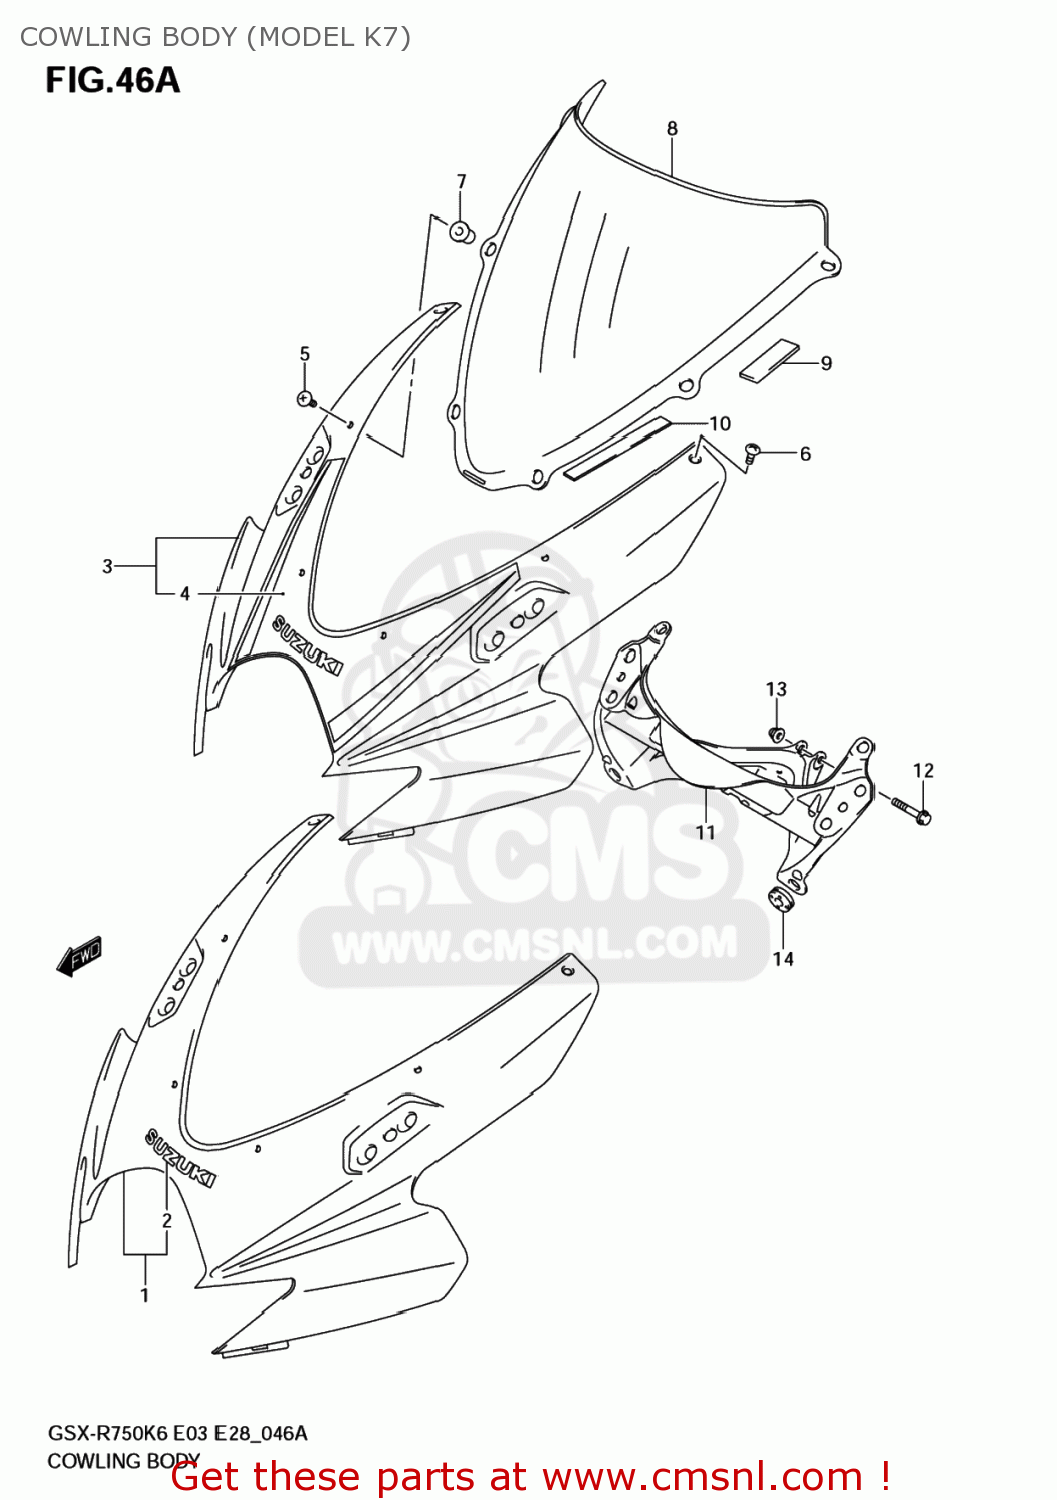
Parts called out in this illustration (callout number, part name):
1	BODY ASSY,COWLING
2	EMBLEM,SUZUKI
3	BODY ASSY,COWLING
4	TAPE SET,BODY COWL
5	SCREW(5X18)
6	SCREW(5X15)
7	NUT
8	WINDSCREEN
9	TAPE(6X25X0.13)
10	CUSHION,WINDSCREEN
11	BRACE,COWLING
12	BOLT
13	NUT
14	CUSHION
